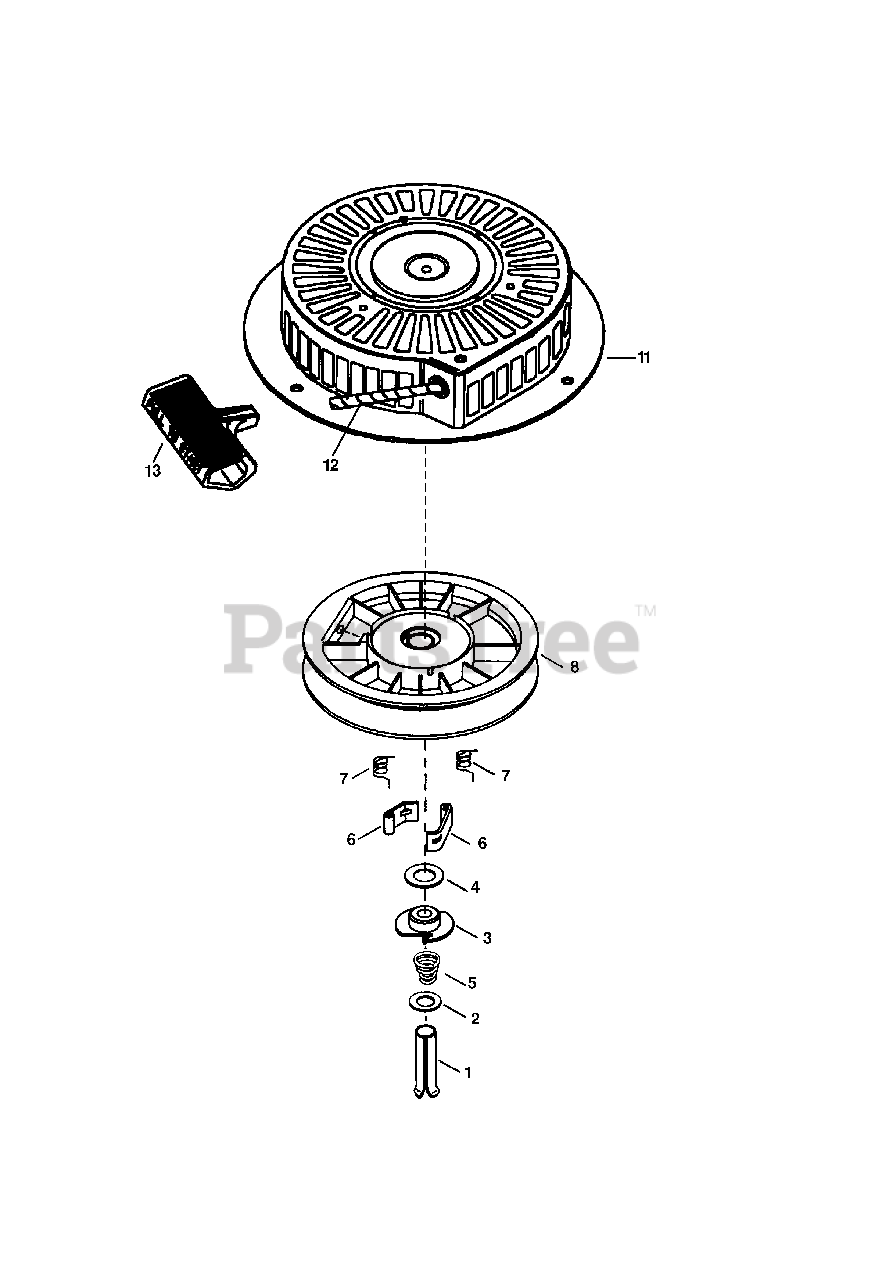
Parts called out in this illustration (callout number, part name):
1	Spring Pin (Incl. 4)
3	Retainer
5	Brake Spring
6	Starter Dog
7	Dog Spring
8	Pulley & Rewind Spring Assembly
11	Starter Housing Assembly
12	Starter Rope also available in 740033 B Starter Rope & Handle Kit
13	Starter Handle (Mitten Grip) (also av ailable in Packaged Part #740053B) st arter)
